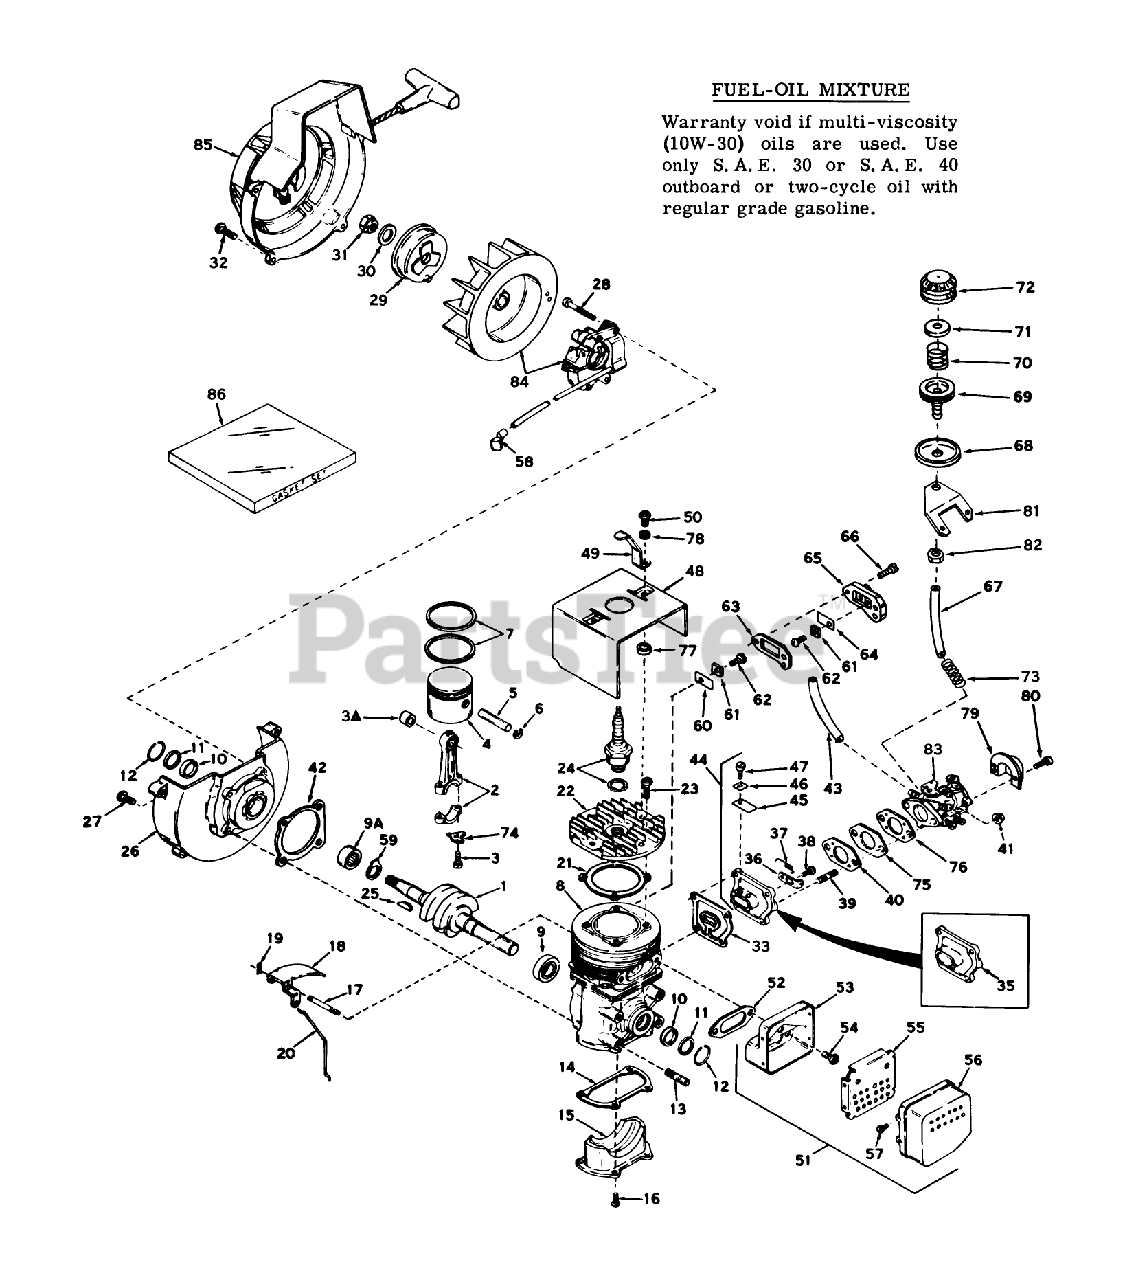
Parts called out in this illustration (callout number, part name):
1	Crankshaft
2	Rod Assy., Connecting (Incl. Nos. 3 3A)
3	Bolt-Rod, Connecting
3A	Bearing, Cartridge
4	Piston
5	Pin, Piston
6	Ring, Piston Pin Retaining
7	Ring Set
8	Block Assy., Cylinder (Incl. Nos. 9, 10 thru 13 17)
9	Bearing Ball
9A	Bearing-Cartridge
10	Seal, Crankshaft
11	Retainer, Crankshaft Seal
12	Spring, Crankshaft Seal
14	Cover-Rubber
15	Plate, Cover
16	Screw (T-25, 10-24 x 1/2)
17	Shaft, Air Vane
18	Vane Assy, Air
19	Clip,Air Vane
20	Link Governor
21	Gasket, Cylinder Head
23	Screw (T-30, 1/4-20 x 3/4)
24	Plug, Spark (J17LM)
25	Key, Woodruff
26	Base Assembly, Shroud (Incl. #9A-12)
27	Screw
28	Screw
29	Cup, Starter
30	Washer, Flat
31	Nut, Flywheel
32	Screw (T-30, 1/4-20 x 3/4)
33	Gasket, Port
35	Adapter, Cover
36	Lever, Adjusting
37	Spring, Adjusting Lever
38	Screw
40	Gasket, Carburetor 1/8" thick)
41	Locknut
42	Gasket, Shroud Base
43	Line-Fuel (8.62)
44	Plate Assy. Reed(Incl. Nos. 45, 46 47j (Type 1450D)
45	Reed Type 1450B
46	Stop, Reed Type 1450B
47	Screw, Pan Flex Hd. type 1450B
48	Shroud, Cylinder
49	Lever, Stop
50	Screw
51	Muffler Assy.
52	Gasket-Muffler
53	Base-Muffler
54	Screw
55	Baffle Muffler
56	Cover Muffler
57	Screw
58	Terminal, Lead wire
59	Washer, Thrust
60	Reed, Compression Release
61	Plate, Reed Hold Down
62	Screw
63	Gasket, Compression Release
64	Reed, Compression Release
65	Cover, Compression Release
66	Screw
67	Line, Primer
68	Retainer, Primer Bulb
69	Body, Primer
70	Spring, Primer Bulb
71	Washer, Primer Bulb
72	Bulb, Primer
73	Spring, Primer line support
74	Washer, Tab
75	Spacer
76	Gasket, Carburetor (1/16"thick)
77	Spacer
78	Washer
79	Baffle-Carburetor
80	Screw
81	Mounting Bracket, Primer
82	Hex nut
83	Carburetor
84	BRACKET S
85	Shroud Starter Assy.
86	Gasket Set
